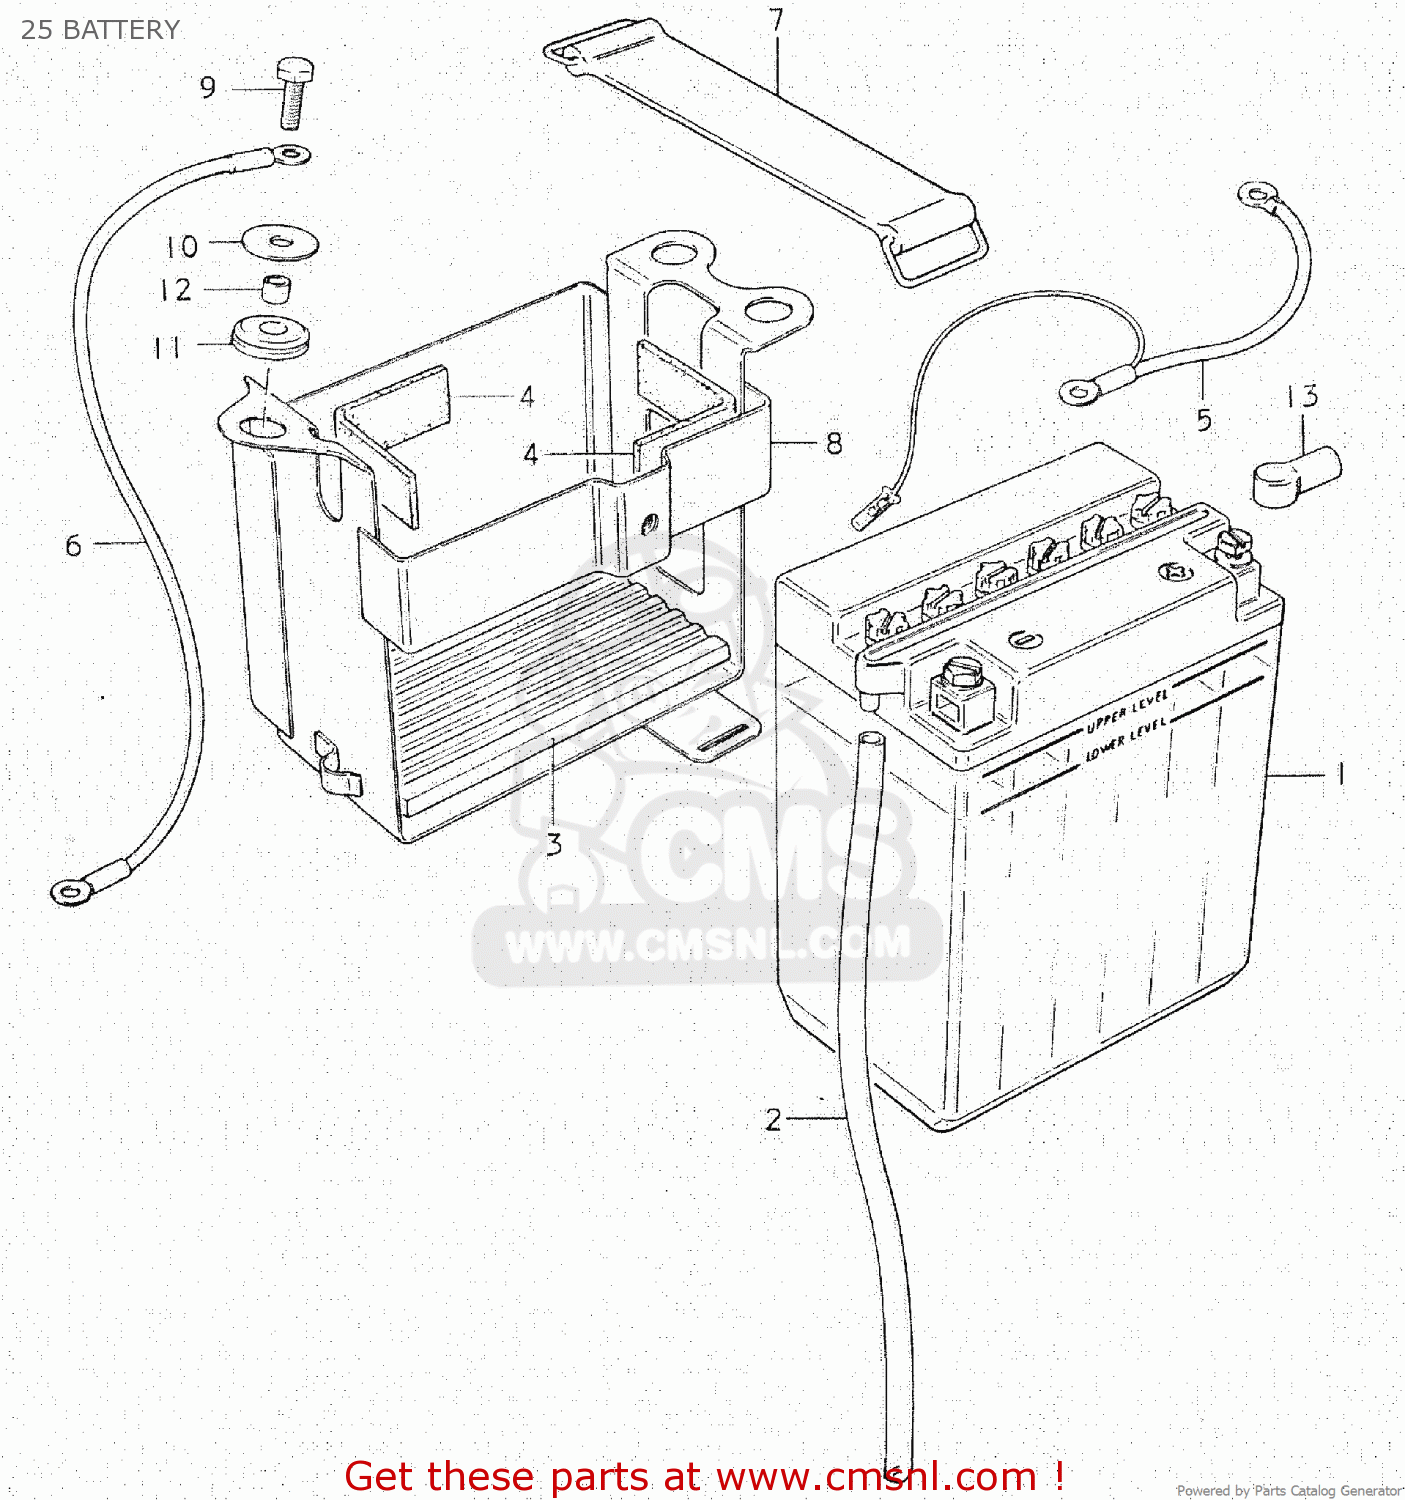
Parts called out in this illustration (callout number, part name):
1	BATTERY ASSEMBLY
2	HOSE,BATTERY EXHAUST
3	PROTECTOR,BATTERY
4	PROTECTOR,20X9
5	WIRE,BATTERY PLUS
6	WIRE,STARTER MOTOR LEAD
7	BAND
8	HOLDER,BATTERY
9	BOLT, UPPER
10	WASHER(6,5X22X1.6)
11	CUSHION
12	SPACER(6.2X8.3X5.7)
13	CAP,TERMINAL
